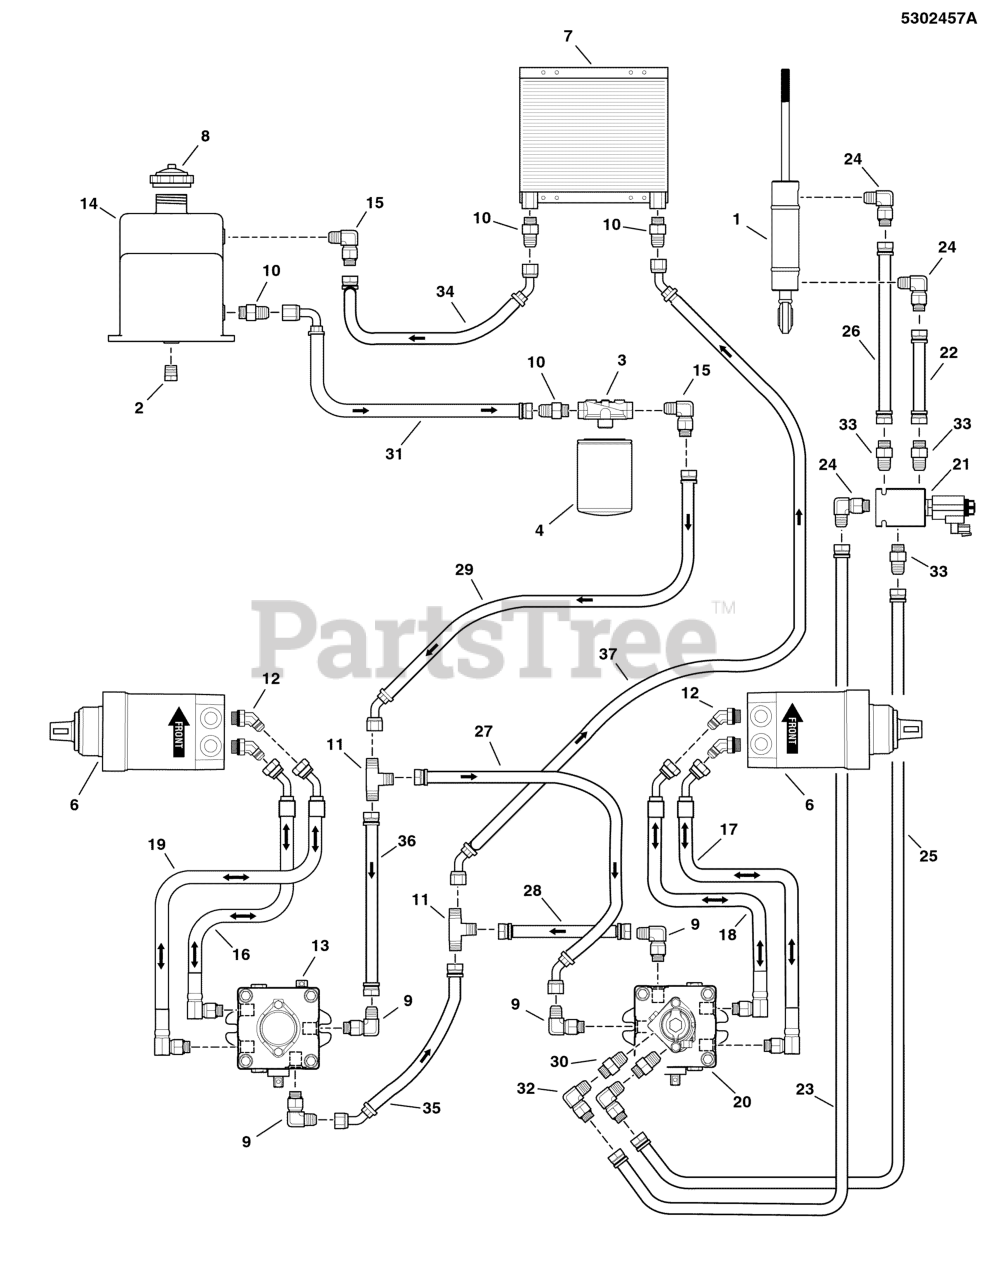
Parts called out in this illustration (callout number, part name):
1	CYL, HYD, 1.5 BORE X 5.5 STROKE
2	PLUG, 1/2NPT, SQUARE HEAD
3	FILTER HEAD
4	FILTER, HYDRAULIC, SERVICE PART (PKG)
6	WHEEL MOTOR-TF0405UB080AADD MB 25
7	OIL COOLER 1.5 X 8.5 X 11
8	CAP, 2-1/2 VENTED
9	FITTING, #8 JIC - #8 O-RING, 90 DEG.
10	FITTING, #8 JIC - 1/2 NPT, STRAIGHT
11	FITTING T JIC #8
12	FITTING, #8 JIC - #10 O-RING, 45 DEG.
13	PUMP, HYDROSTATIC - PW - 1ACC
14	HYDRAULIC RESERVIOR
15	HYDRALIC FITTING, MALE ELBOW
20	PUMP, DECK LIFT, PW-1DCC-QY1X-XXXX
21	VALVE, HYD, 4 WAY, 2 POSITION
22	HOSE ASSEMBLY (20.5) LP, ST & ST END
23	HOSE ASSEMBLY (36.5) LP, ST & ST ENDS
24	FITTING, 90DEG, #6 JIC TO #6 ORING MALE
25	HOSE, ASM, 41.5", IS5100 DECK LIFT
26	HOSE ASM, IS5100 DECK LIFT
27	HOSE ASSEMBLY (7) LP, 4 ST & 45 ENDS
28	HOSE ASSEMBLY (15) LP, ST & ST ENDS
29	HOSE ASSEMBLY (24.5) LP, ST & 45 ENDS
30	FITTING, STR, #6JIC TO #4 ORING, MALE
31	HOSE ASSEMBLY (21.5) LP, ST & 90 ENDS
32	FITTING, 90DEG, #6 JIC MALE-#6JIC SWIVEL
33	FITTING, #6JIC-#6 ORING, STR. MALE-MALE
34	HOSE ASSEMBLY (64) LP, ST & 45 ENDS
35	HOSE ASSEMBLY (9) LP, ST & 45 ENDS
36	HOSE ASSEMBLY (16.5) LP, ST & ST ENDS
37	HOSE ASSEMBLY (64) LP, 45 & 45 ENDS
